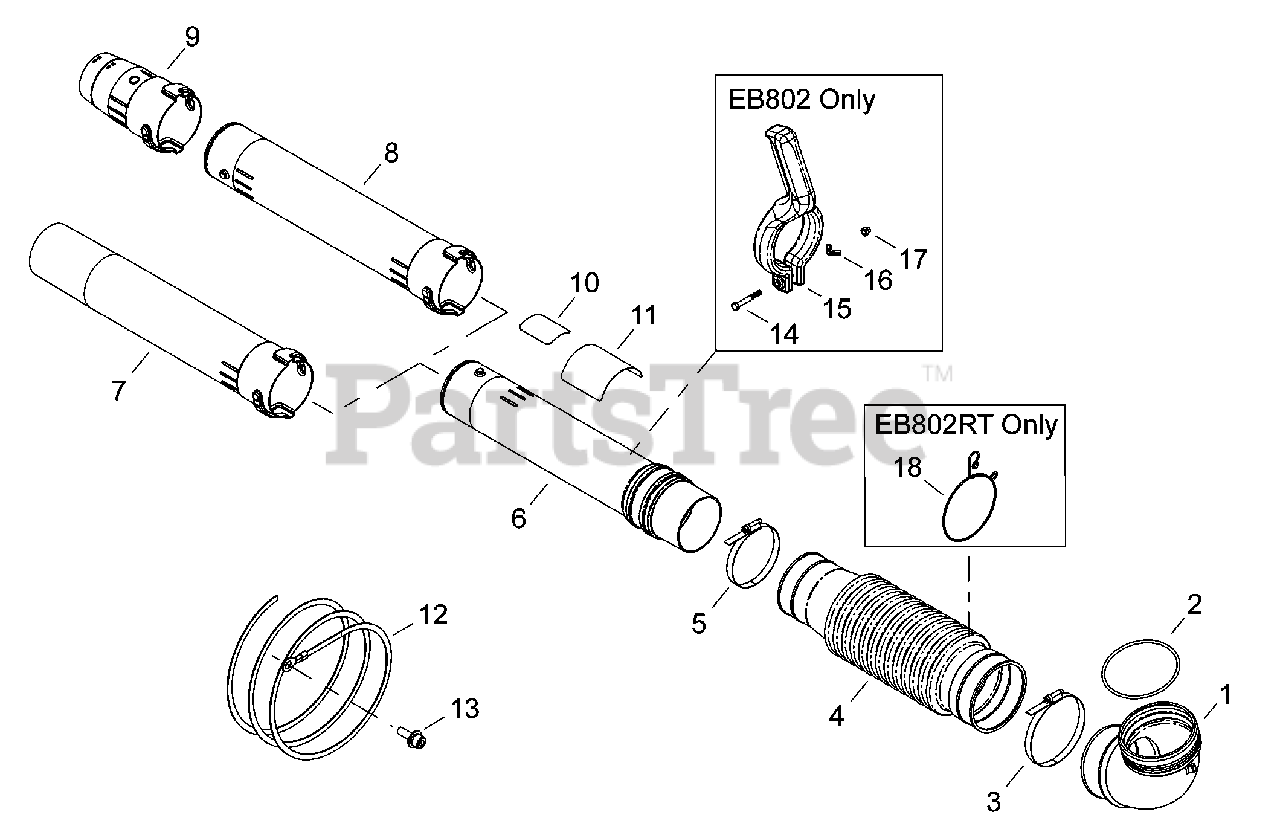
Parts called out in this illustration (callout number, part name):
1	TUBE, BLOWER - ELBOW
2	O-RING
3	CLAMP
4	TUBE, BLOWER - FLEXIBLE
5	CLAMP
6	TUBE, BLOWER - SWIVEL
7	TUBE, BLOWER - NOZZLE
8	TUBE, BLOWER - STRAIGHT
9	TUBE, BLOWER - NOZZLE
10	LABEL, CAUTION
11	LABEL, SHINDAIWA PROFESSIONAL
12	WIRE, STATIC DISCHARGE 1050 MM
13	BOLT M5×16
14	BOLT 6×60
15	HANDLE
16	NUT, WING M7
17	NUT M6
